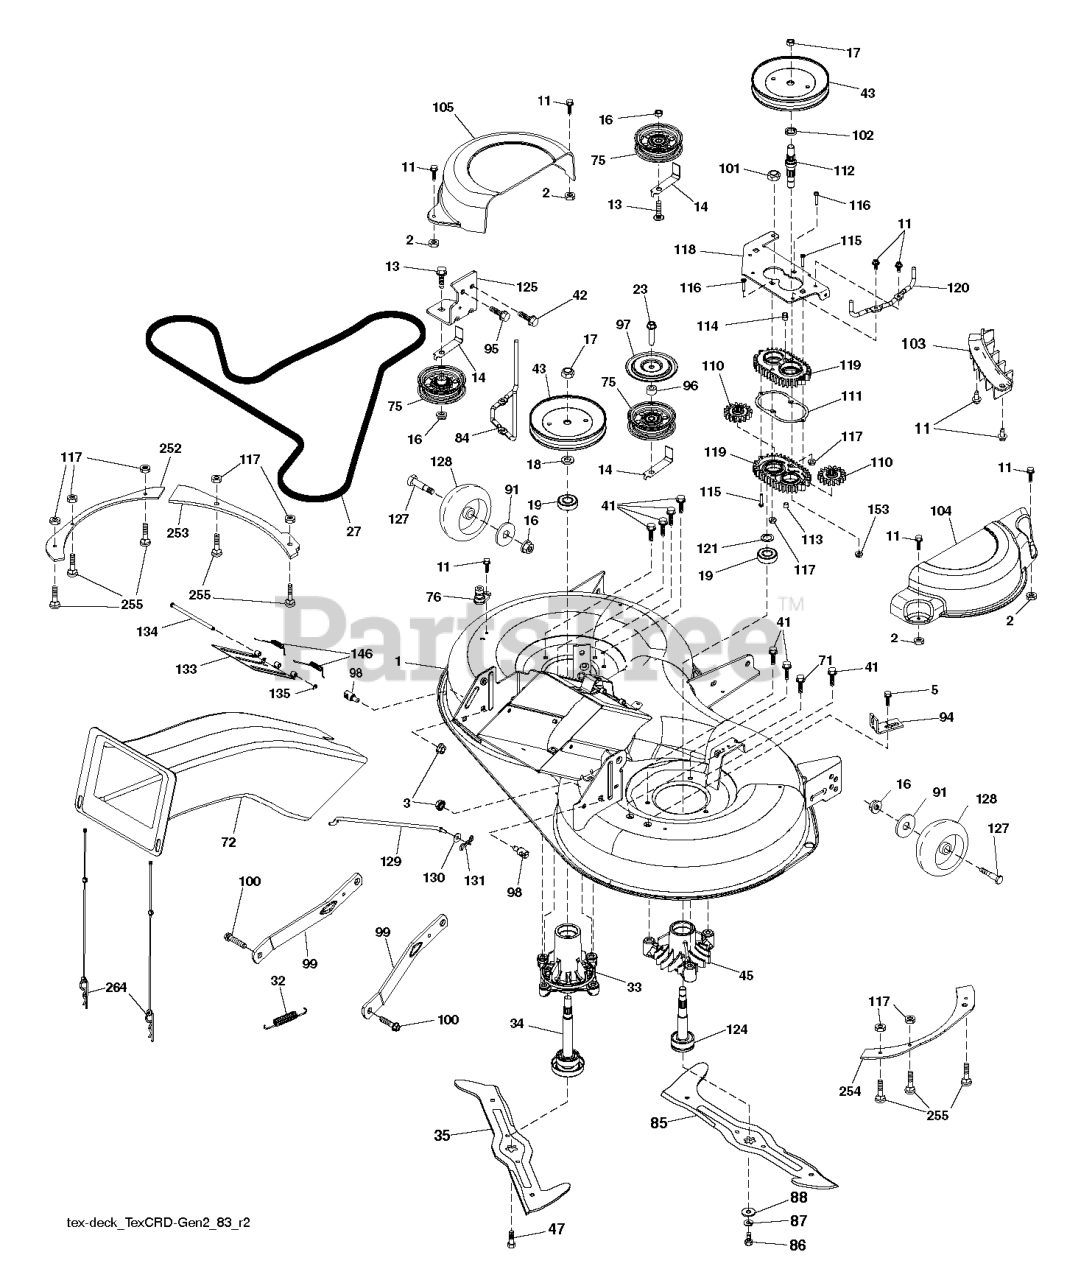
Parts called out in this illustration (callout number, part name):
1	DECK.SVC.WLDT.97EL.TCRD.EZ.498
2	PALNUT 1/4
3	NUT LOCK HEX FLANGE 5/16-18
5	BOLT.5/16HEX.WHS.HD
11	SCREW.1/4-20X5/8
13	BOLT.3/8-16X1.50
14	KEEPER, BELT IDLER
16	NUT LOCK FLG 3/8-16 UNC
17	NUT.FLANGE.LOCK.TOP
18	WASHER.SPACER.MANDREL
19	RP.HOUSING.MANDREL.4PT.
23	SCREW LT
27	BELT 97CM ELECTRIC
32	SPRING 107CM & 97CM ELECTRIC D
33	RP.HOUSING.MANDREL.4PT.
34	SHAFT ASM.MNDRL.N/GREASEABLE
35	BLADE.3N1.LH.CRD.97
41	BOLT.HEX.WASHR.HED.313-18X1.19
42	SCREW
43	PULLEY.MANDREL.5.0.PD.38"
45	HOUSING.MANDREL.44/46" VENT
47	SCREW.SEMS.7/16-20X1.HEX.HEAD
71	SCREW 3/8-16X1/2
72	CHUTE.SLOTTED.HOLES.TEX.CRD.II
75	FLAT IDLER PULLEY
76	PORT.WASHOUT
84	BELT KEEPER.MANDREL.38"COATED
85	BLADE.3N1.RH.CRD.97
86	BOLT.3/8-24X1.25GR8. LHTHRD
87	SLW 3/8 STD
88	WASHER.BLADE
91	WASHER.5/16.FLAT.STE.STD.
94	BRKT.CLUTCH.CABLE
95	SCREW, 3/8-16X3/4
96	SPACER
97	PROTECTOR
98	STUD.FASTNER.W/ANTI-ROTATE
99	ARM.SUSPENSION.MOWER.R
100	BOLT.SHOULDER
101	NUT.CROWNLOCK.9/16 -18.UNC
102	SPACER BEARING
103	GUARD GUARD FRONT VENT
104	97.CRD.RH.MANDREL.COVER
105	MANDREL MANDREL COVER LH
110	CRD.SPUR.GEAR
111	GASKET GASKET GEARCASE
112	SHAFT SHAFT. CRD GEARCASE ADAP
113	PLUG PLUG OIL
114	VENT.BREATHER.1/8 NPT
115	SCREW
116	BOLT.CARIGE.SS.1/4-20X1.75GR5
117	NUT T
118	ARM ARM CLUTCHING
119	GEARCASE GEARCASE SUBASM
120	BRACKET KEEPER BELT RH
121	WASHER WASHER
124	MANDREL SHAFT NON/GREASE
125	BRACKET
127	BOLT.SHOULDER.3/8-16X3-5/8.
128	WHEEL.GAUGE.RALLY
129	ROD ROD. SWAY CRD GEN II
130	WASHER
131	PIN.COTTER.5/16.BOW TI
133	DOOR
134	PIN PIN.HINGE
135	E-RING.5/16"
146	SPRING SPRING: EZ MULCH DOOR
153	NUT HEXAGON 9/16-18 G2 ZPB LOC
252	PLATE.REINFORCEMENT.X431
253	PLATE.REINFORCEMENT.LHS.X431
254	PLATE.REINFORCEMENT.LHS.X431
255	RHSNB, 1/4-20 X 1, GR5
264	RETAINER.ASM.UPPERCHUTE.CRD2.5
